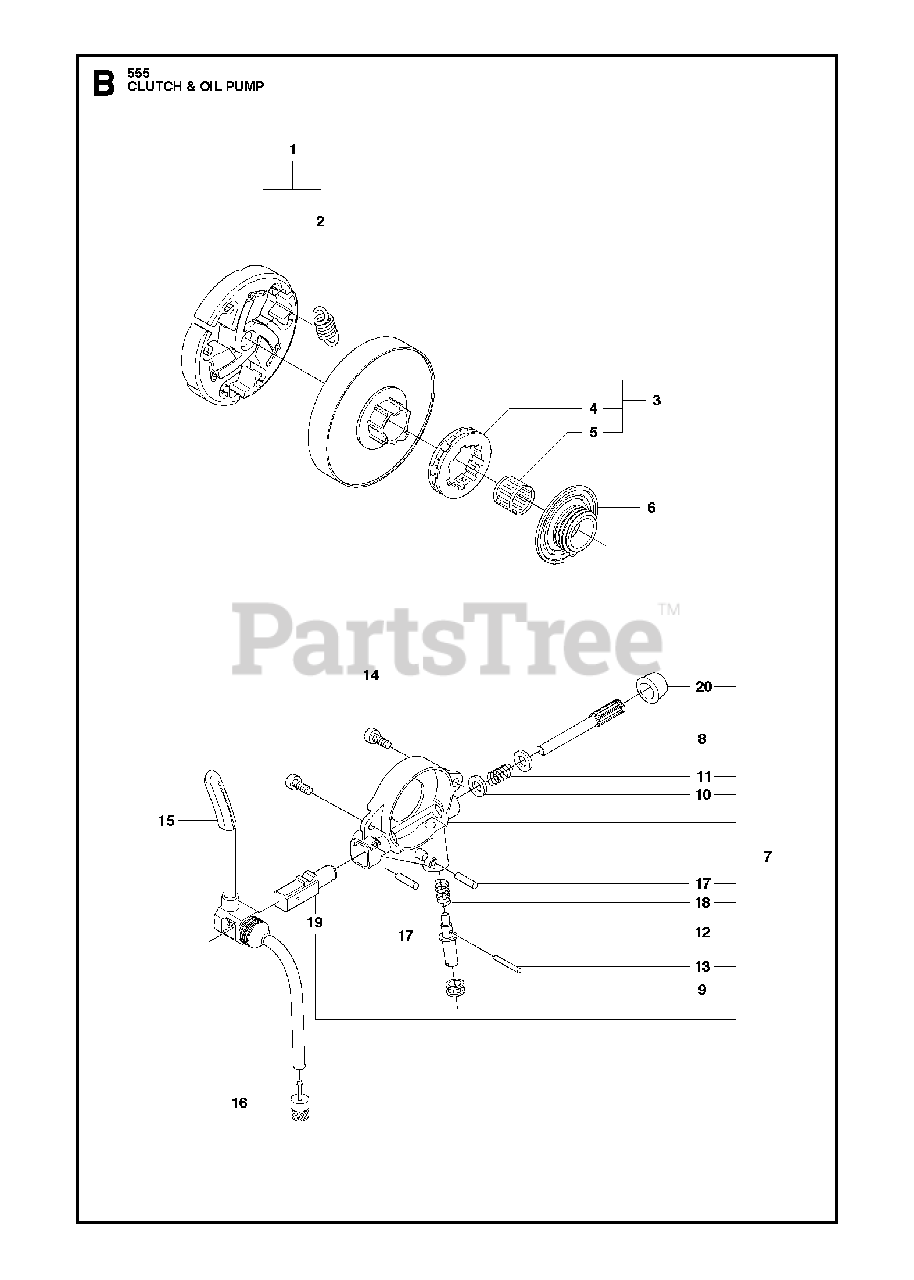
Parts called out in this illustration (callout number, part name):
1	CLUTCH ASSY
2	SPRING
3	RP CLUTCH DRUM ASSY
3	CLUTCH DRUM ASSY
4	RIM SPROCKET 7T .325
4	68210 RIMSPROCKET
5	NEEDLE BEARING
6	WORM WHEEL
7	OIL PUMP ASSY
8	PUMP PISTON
9	CASING
10	WASHER
11	SPRING
12	RP ADJUSTING SCREW
13	PIN
14	SCREW IHSCM
16	OIL PLUMMET
17	PIN 3X10
18	SPRING
19	PUMP CYLINDER
20	SEALING PLUG
